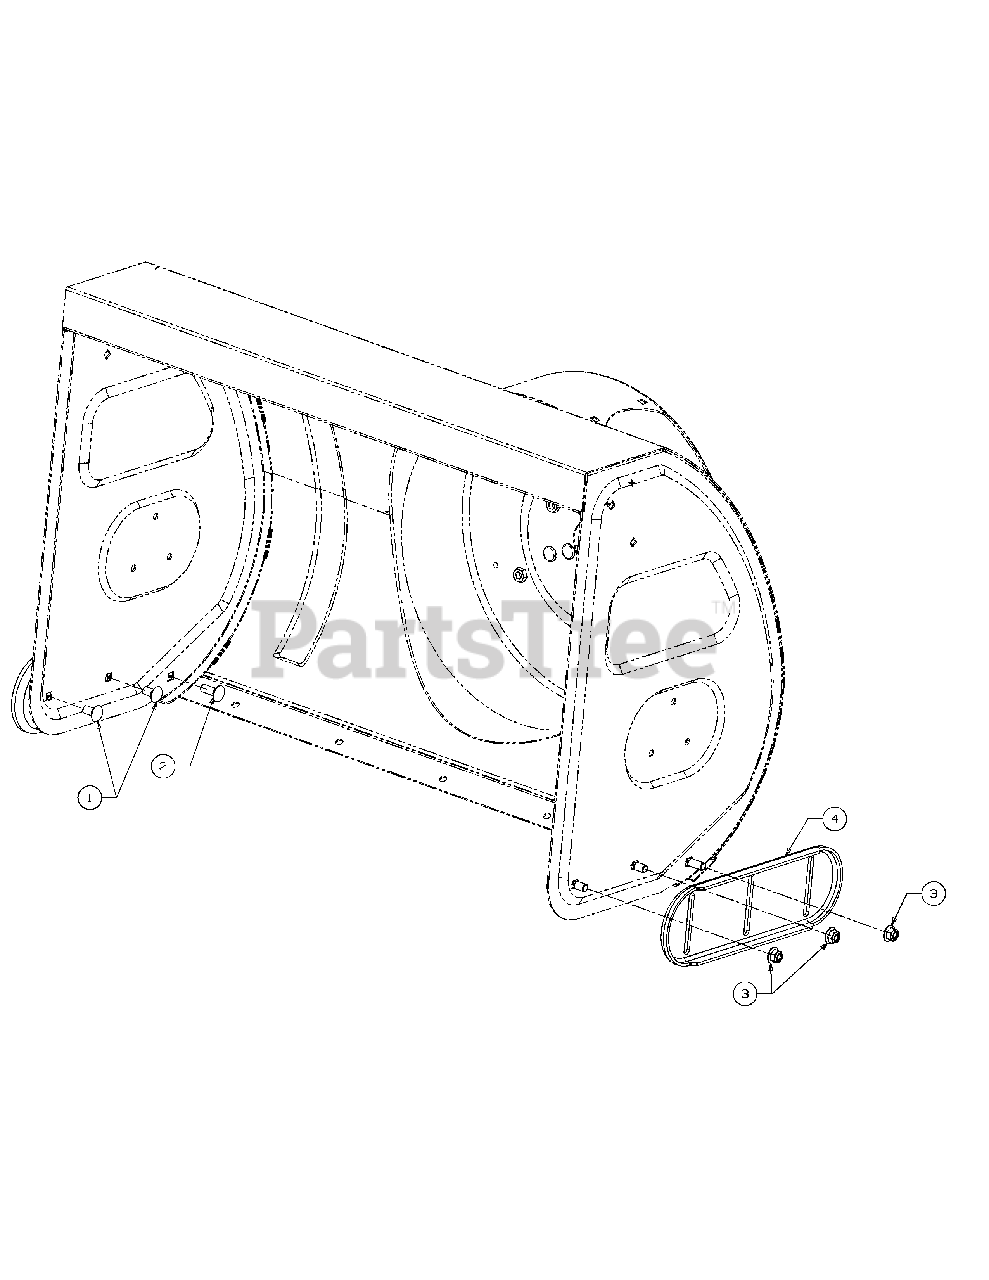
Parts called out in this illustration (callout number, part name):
1	Bolt:Crg:3/8-16:.750
2	Bolt:Crg:3/8-16:1.00:Gr1
3	Nut:Flglk:3/8-16:Grf:Nylon
4	Skid Shoe, Steel
